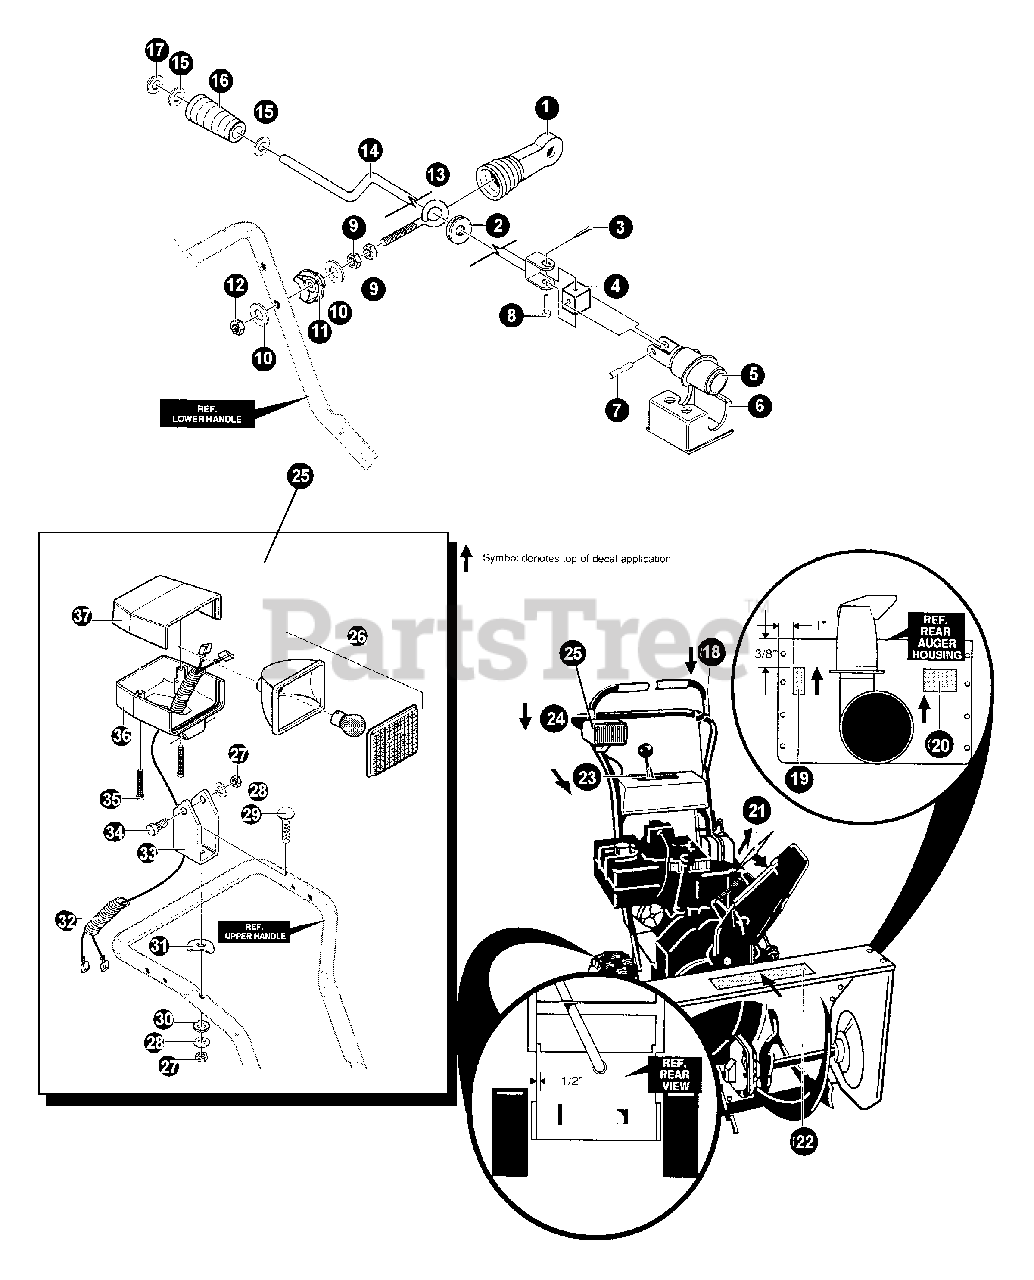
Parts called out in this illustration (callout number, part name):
1	BOOT, EYEBOLT CHUTE
2	GROMMET, EYE BOLT
3	PIN, COTTER
4	BLOCK, UNIV PIV
5	GEAR, WORM
6	BRACKET, WORM MTG
7	PIN, U-JOINT
8	PIN, CLEVIS
9	NUT, 3/8"-16
10	WASHER
11	ADAPTER, BOOT
12	NUT, 3/8"-16
13	BOLT - 3/8-16×5 -- EYE
14	CRANK ASSY
15	WASHER, FLAT
16	HANDLE, CHUTE CRANK
17	E-RING
18	LABEL - TRACTION DRIVE ENGAGE
19	LABEL - DANGER
20	LABEL - DANGER
21	LABEL - DANGER
22	LABEL - ECHO
23	LABEL - GEAR SELECTOR
24	LABEL - AUGER DRIVE ENGAGE
25	HEAD LIGHT KIT 8/10 H.P.
26	HOUSING, HEAD LIGHT
28	WASHER
29	BOLT, 5/16-18×2.25
30	WASHER
31	WASHER, SADDLE - 5/16"
32	WIRING, HARNESS ASSY
33	BRACKET, HEADLIGHT
34	SCREW, 5/16-18×2.00 HHCFT
35	SCREW - 8×1.75"
36	CASE, HEADLIGHT - LOWER
37	HOUSING, HEADLIGHT UPPER
